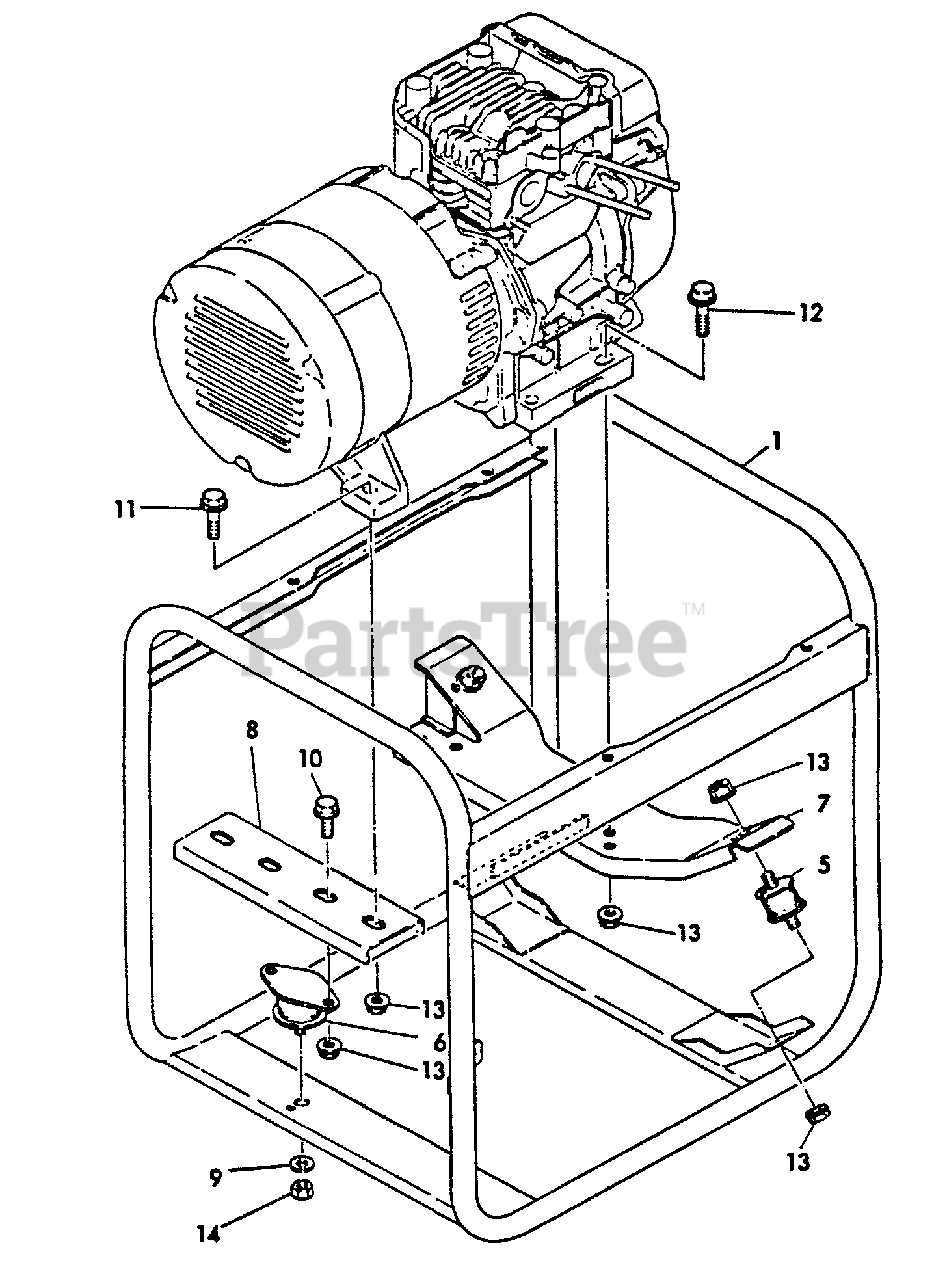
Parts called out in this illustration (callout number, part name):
1	FRAME ASSY
5	DAMPER, FRONT
6	DAMPER, REAR
7	STAY, DAMPER
8	STAY, REAR DAMPER
9	LOCKWASHER - 10
10	BOLT - 8X20 -- PLATED
11	BOLT - 8X30 -- PLATED
12	BOLT - 8X38 -- PLATED
13	NUT - 8
14	NUT - 10
